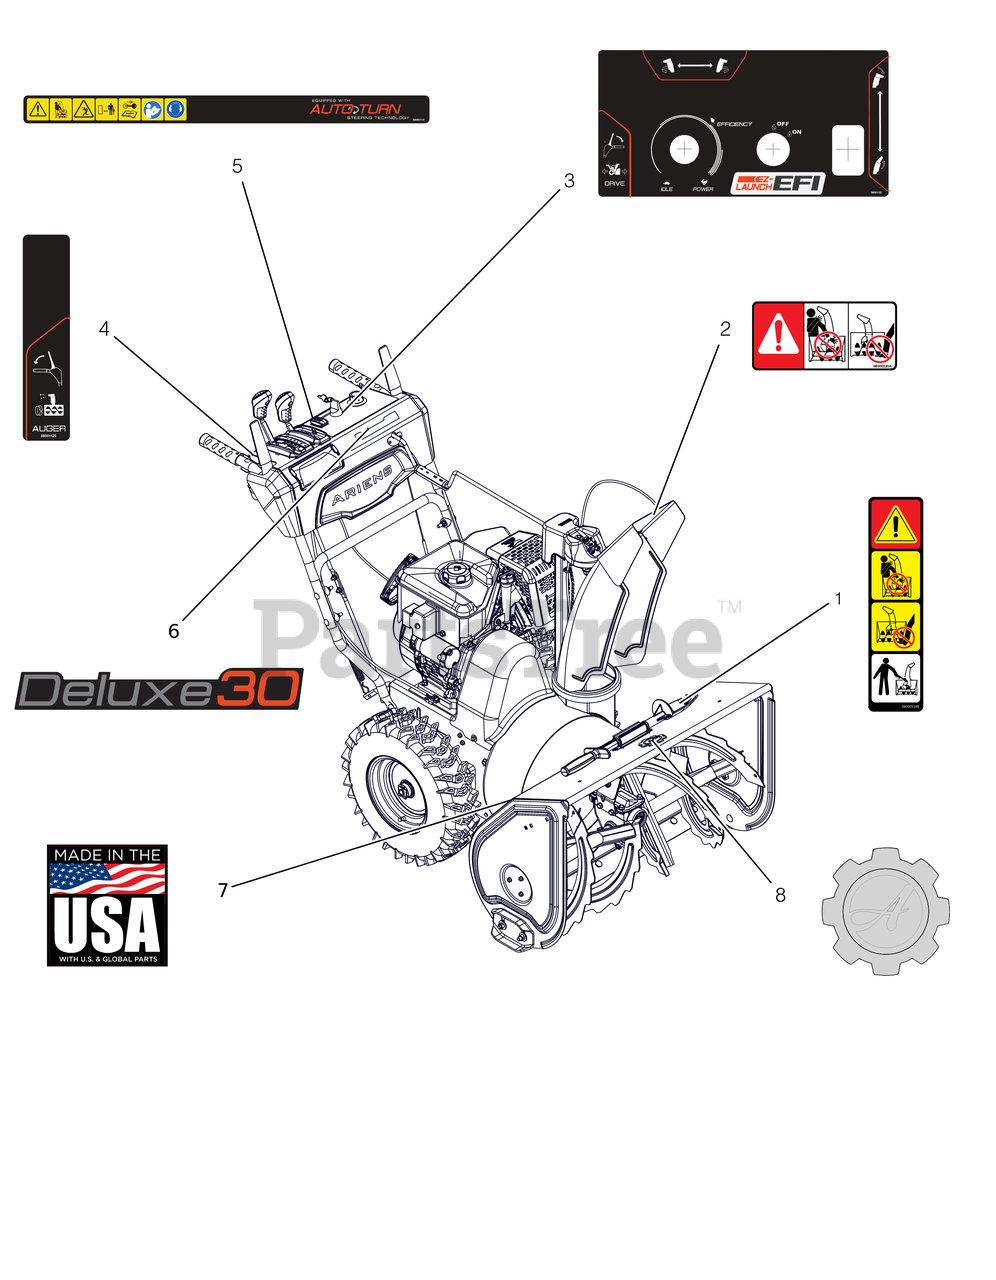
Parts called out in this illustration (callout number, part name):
1	DECAL, DANGER - ROTATING PARTS
2	DECAL, DANGER
3	DECAL, CONTROL - ID EFI W/GEL
4	DECAL,CONTROL-RH CONTROL
5	DECAL,DASH - SAFETY/EFI
6	DECAL, DASH - DELUXE 30
7	DECAL, MADE IN USA
8	DECAL, ARIENS-GEAR BADGE -THK
